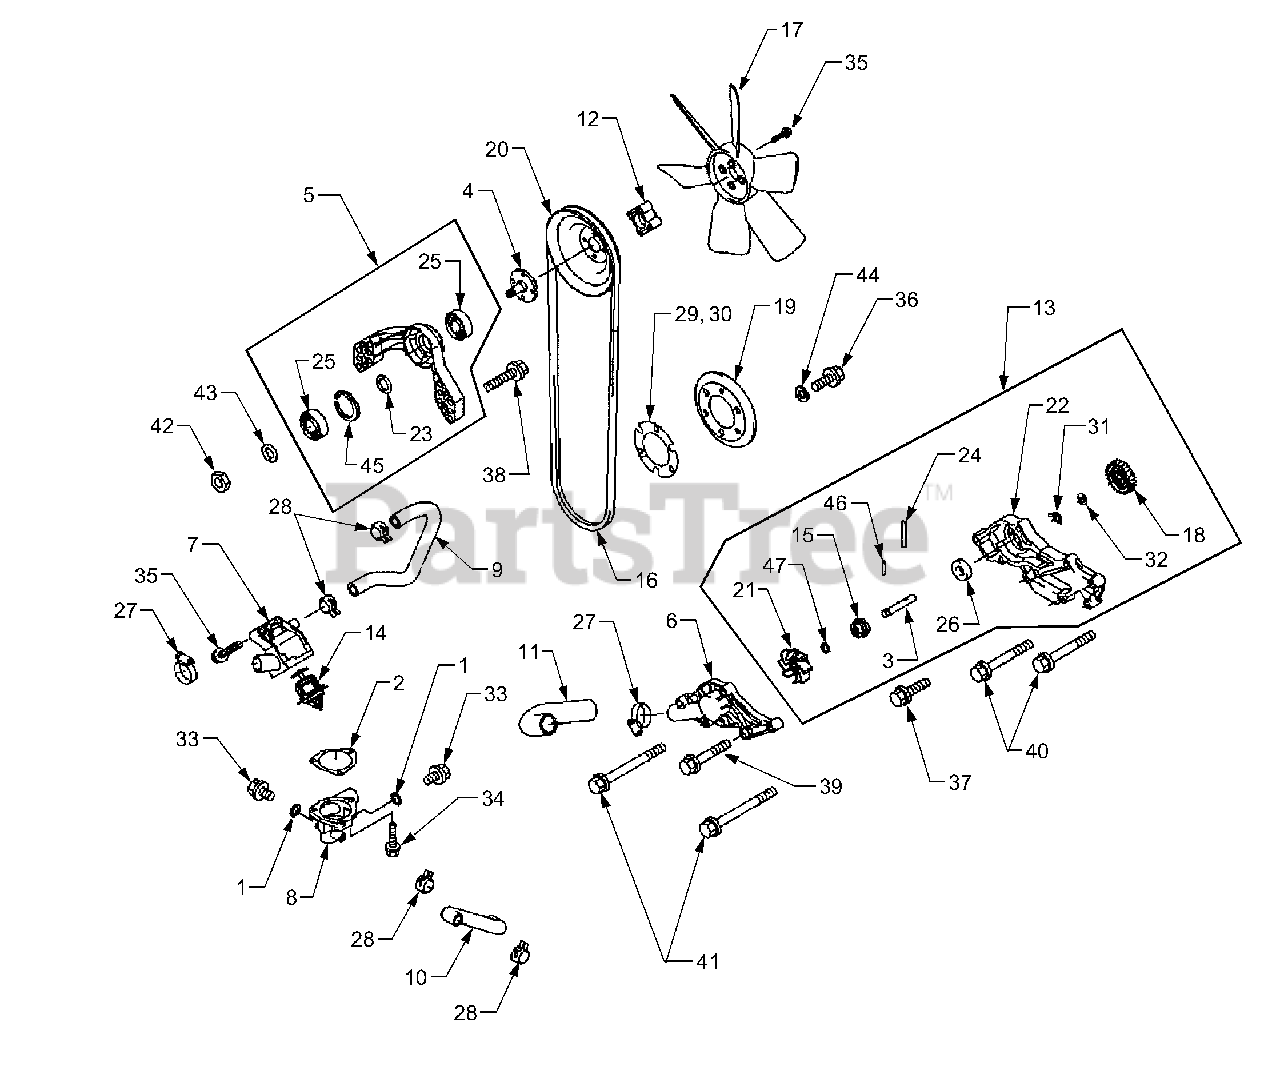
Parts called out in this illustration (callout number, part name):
2	Gasket, Thermostat
3	Shaft, Impeller
4	Shaft, Pulley
5	Housing Assembly
7	Body, Upper
9	Hose, Cooling
10	Hose, Cooling
11	Hose, Cooling
13	Pump Assembly, Water
15	Seal, Mechanical
18	Gear, Spur, 25T
23	Spacer, 12 x 18 x 1.4
25	Bearing, Ball
32	Washer 10.2 x 19 x 0.8
33	Bolt, Flanged
34	Bolt, Flanged
35	Bolt, Flanged
36	Bolt, Flanged
37	Bolt, Flanged
38	Bolt, Flanged
39	Bolt, Flanged
40	Bolt, Flanged
41	Bolt, Flanged
42	Nut, Hex Fine
43	Washer, Plain
44	Washer, Spring
